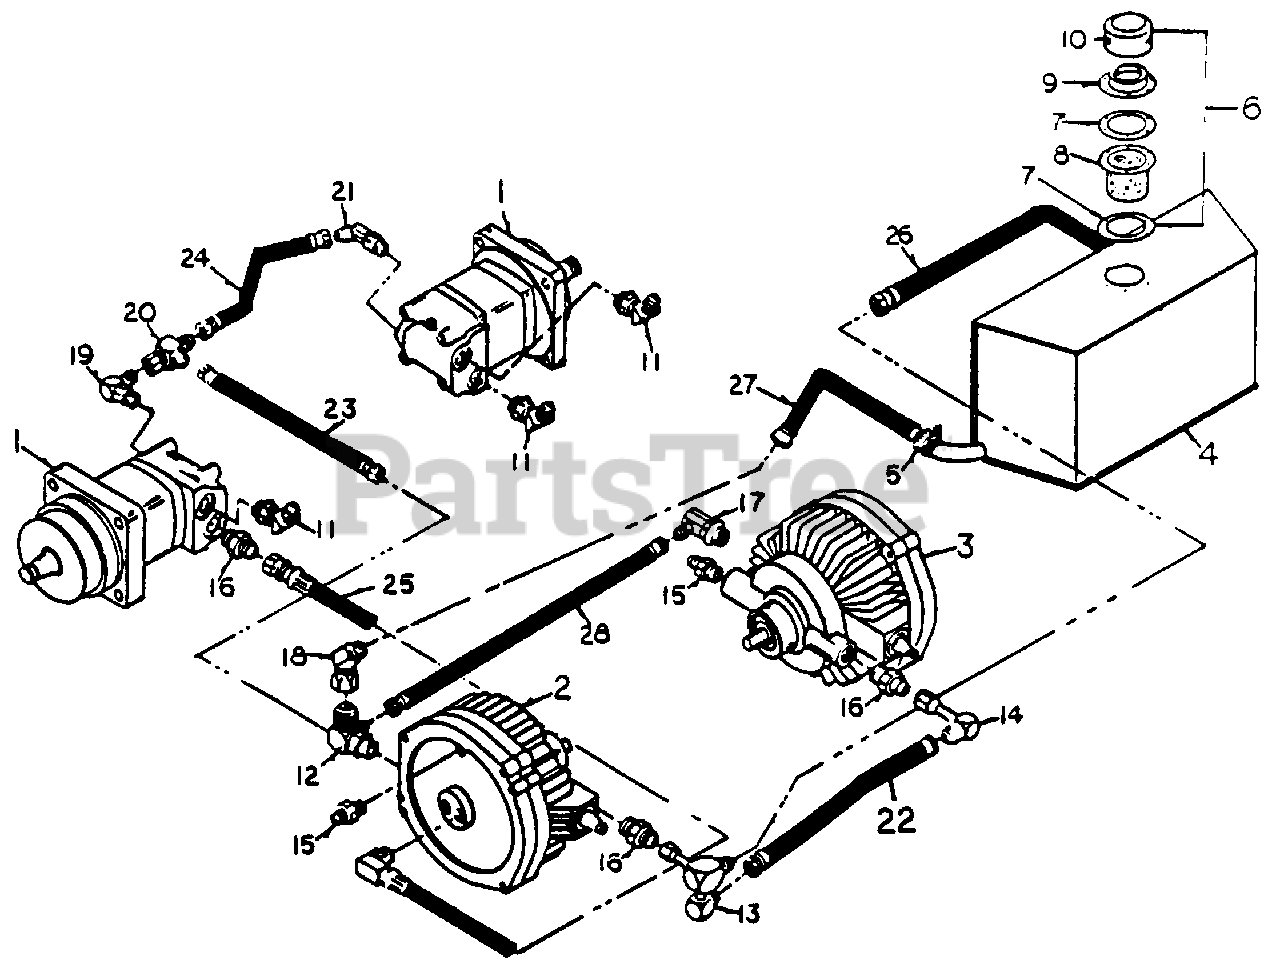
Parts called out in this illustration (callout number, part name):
3	Pump, RH
4	Hydraulic Oil Tank
5	Hose Clamp
6	Hydraulic Fill Cap Assembly
8	Serainer
9	Flll Neck
11	Male Tube, 45ø Male O-ring Adapter
13	Special Adpter
14	Male Tube, 90ø Female Swivel Adapter
15	Male Tube, Male O-ring Adapter
16	Male Tube, Male O-ring Adapter
17	Male Tube, 90 O-ring Adapter
18	Male Tube, 45ø Female Swivel Adapter
19	Male Tube, 90ø Male O-ring Adapter
20	Male Tube, Female Swivel Tee
21	Male Tube, 45ø Female Swivel Adapter
22	Hose, 1/2ID x 18" Long, Easy Couple
23	Hose, 1/4ID x 14" Long, Easy Couple
24	Hose, 1/4ID x 20" Long, Easy Couple
25	Hose, 1/2" ID x 36 1/2" Long
26	Hose, 3/4ID 22" Long, Easy Couple
27	Hose, 3/4" ID x 18" Long Easy Couple
28	Hose, 1/2" ID x 20" Long, Easy Couple
